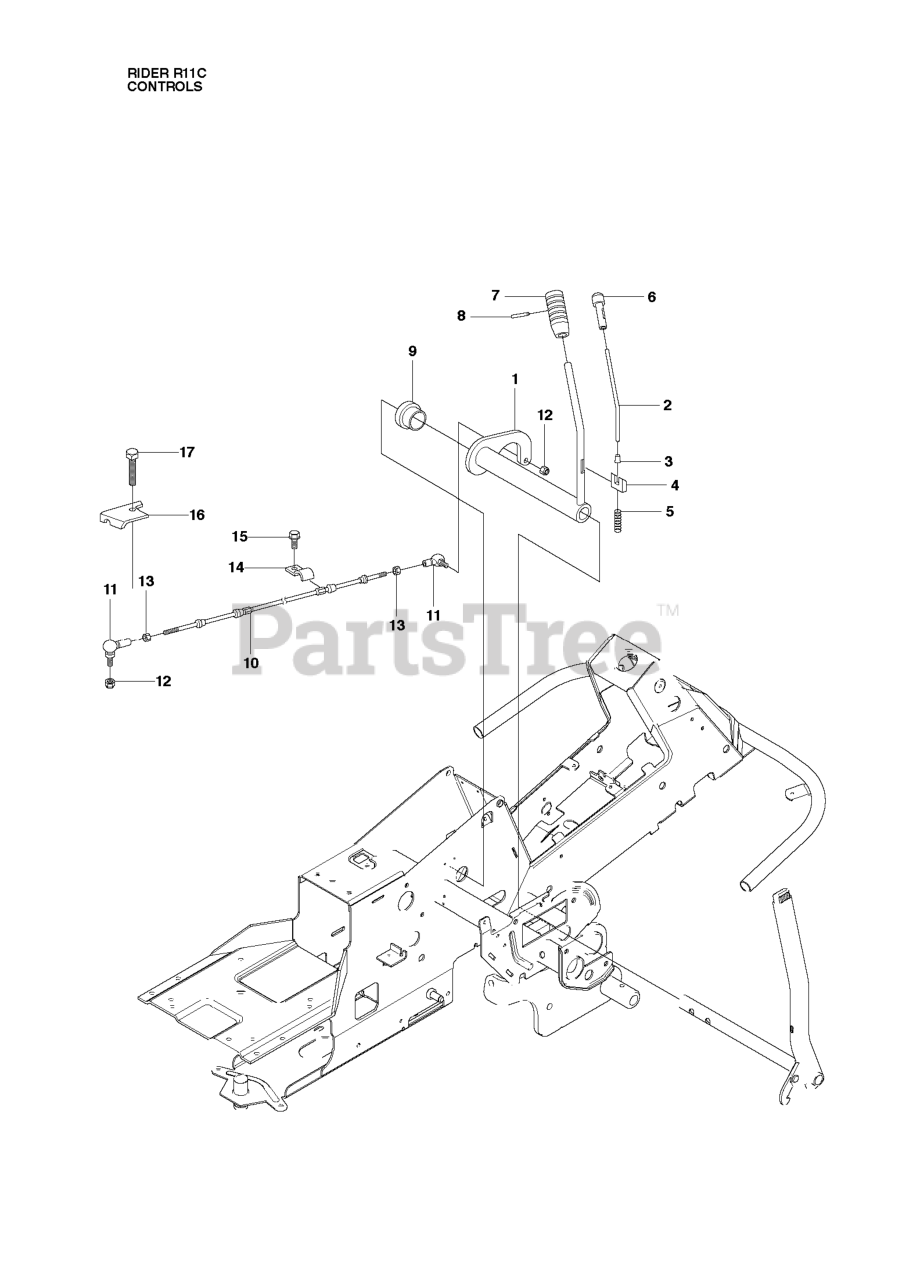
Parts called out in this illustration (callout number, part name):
8	SPRING PIN 3X24
9	BEARING FLANGE
10	CONTROL CABLE
11	CONNECTOR
12	LOCKNUT M5
